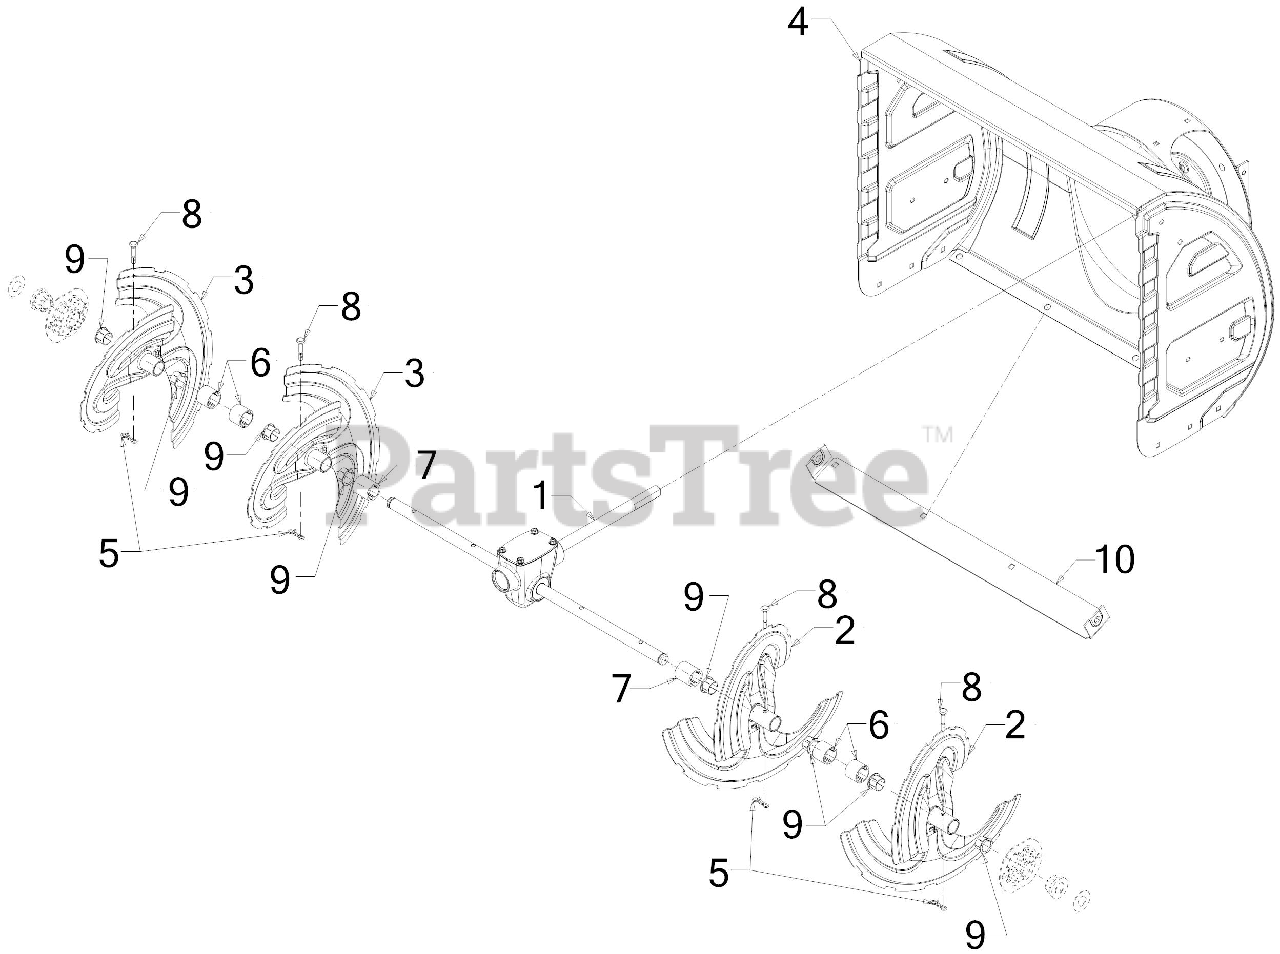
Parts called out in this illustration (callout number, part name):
1	26" AUGER GEARBOX ASSEMBLY
5	BOW TIE COTTER PIN 1/4-5/16
6	SPACER 1.25OD x .75ID X1.00 LG
7	SPACER 1.25OD x .75ID x 1.312 LG
8	SHEAR PIN .25 x 1.50 GR2
9	FLANGE BUSHING
